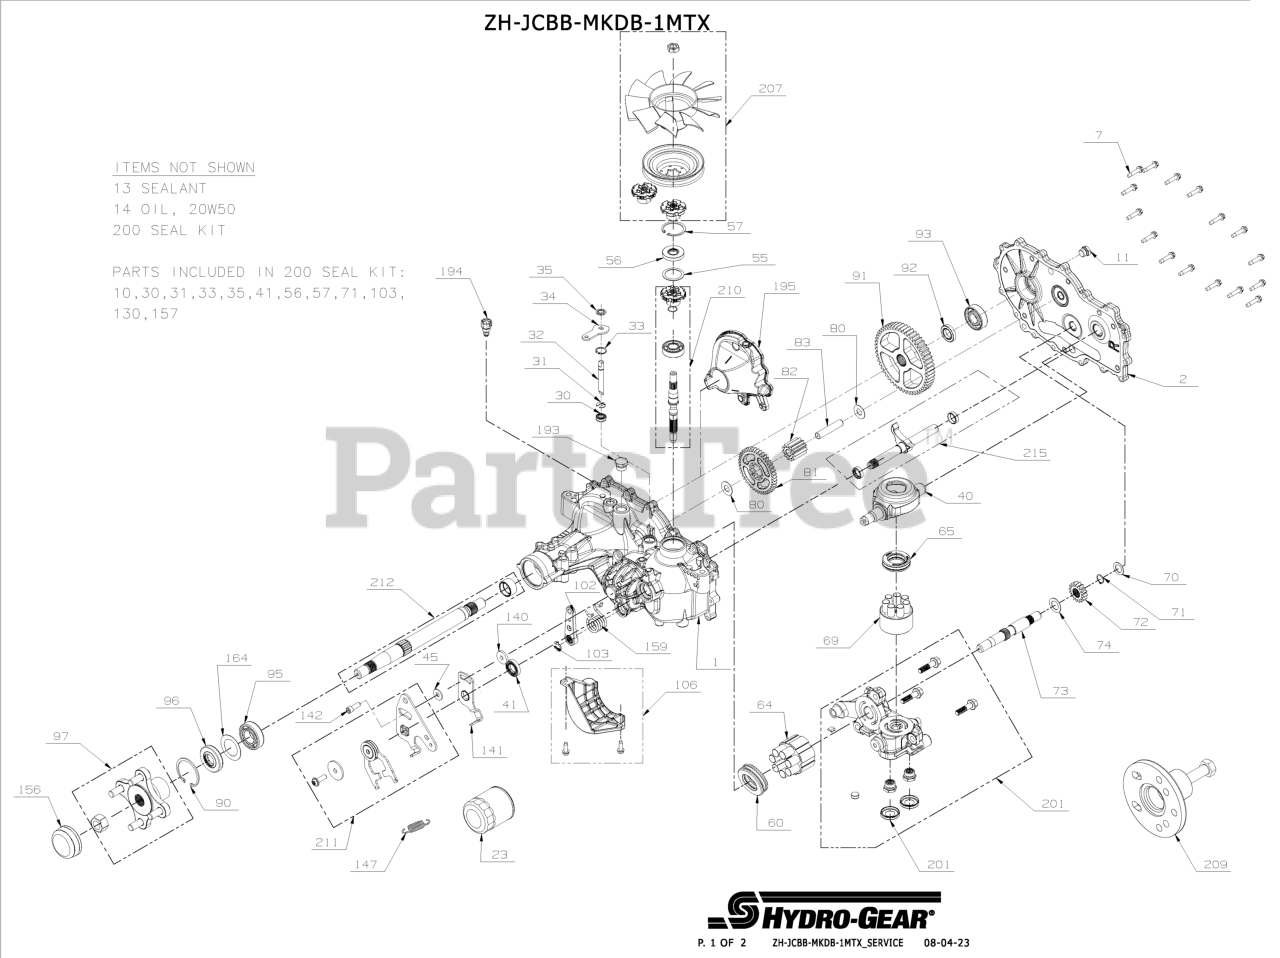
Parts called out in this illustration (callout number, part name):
1	KIT, HOUSING, MAIN, RH, CNTL
2	KIT, SIDE COVER, RH
7	SCREW,HEX WASHER 1/4-20X1.125
11	PLUG EXT HEX VENT 9/16 18
13	SEALANT TUBE 10.1OZ.
14	FLUID, HYDRO 15W50 QT
14	FLUID, HYDRO 20W50 QT
23	FILTER, HYDRO-GEAR 2800 TRANS
30	Seal, lip .375 x 375 x 325
31	RING. RETAINING
32	ROD, BYPASS
33	RING, RET .750
34	ARM, BYPASS
35	RING, RTNG .
40	TRUNNION, SWASHPLATE
41	SEAL, LIP 18X32X7
55	WASHER 1.23X1.56X.04
56	SEAL, LIP 17 X 40 X 7 HNBR
57	RING, RET 1.56 INT
60	HG THRUST BEARING (51462)
64	HG 16CC CYLINDER BLOCK (71579)
65	BEARING. THRUST 30 X 52 X 13
69	ASSY, BLOCK 7 PISTON
70	WASHER .63X1.0X.05
71	RING, RET 62 EXT
72	GEAR 16 TOOTH
73	SHAFT, MOTOR
74	WASHER .71 X 1.16 X .04
80	WASHER .5X1.0X.032
83	PIN, JACKSHAFT
90	RING, RETAINING
91	GEAR 54 TOOTH
92	SPACER
93	KIT, BEARING
95	BEARING 25.4 X 52 X 15 BALL (6205R)
96	SEAL, LIP
97	KIT, HUB 4 BOLT
102	HANDLE- ACTUATING
103	CLIP,BRAKE ARM HYDROGEAR 52027
106	KIT FILTER GUARD
141	ARM, NEUTRAL RIGHT
142	SHCS 5/16-24X1 PATCH
147	SPRING, EXTENSION
156	CAP, AXLE
159	SPRING, TORSION CCW
164	WASHER, 1.355 x 2.035 x .021 FLAT
194	ASSEMBLY, FITTING 9/16-18 BREATHER
195	ASSEMBLY, TANK, EXPANSION, INTERNAL, RH
200	KIT, SEAL
201	KIT, CENTER SECTION, RH
207	KIT, FAN / PULLEY
209	HUB PULLER 5 BLT
210	KIT, INPUT SHAFT
211	KIT RTN BIDIRECTIONAL
212	KIT SHAFT AXLE
215	KIT, OUTBOARD, RH ROT A / LH ROT B
